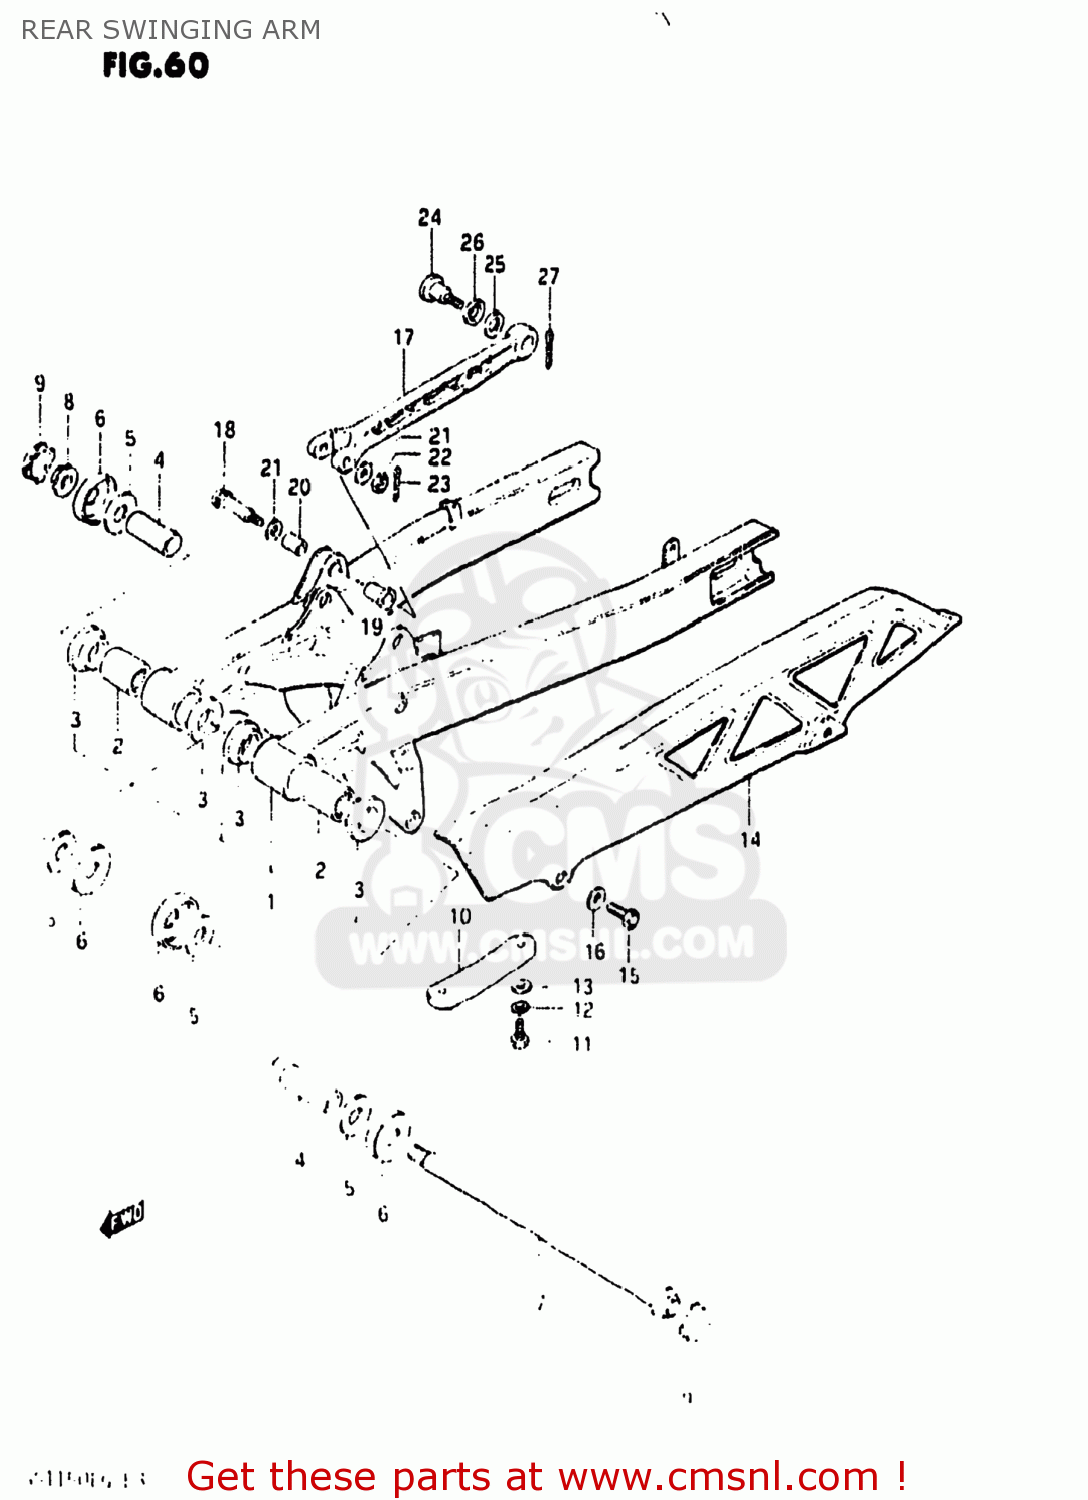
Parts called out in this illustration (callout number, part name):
1	ARM,REAR SWING
2	BEARING(25X33X30)
3	BUSHING
4	SPACER,RR SWINGING ARM PIVOT
5	WASHER
6	COVER,RR SWINGINGARM PIVOT
7	SHAFT,REAR SWING ARM
8	NUT
9	CAP,PIVOT
10	BUFFER,CHAIN TOUCH DEFENSE
11	BOLT
12	WASHER,LOCK
13	WASHER(6.5X18X1)
14	CASE,CHAIN
15	BOLT
16	WASHER
17	LINK,REAR TORQUE
18	BOLT 8X60
19	SPACER,REAR TORQUE LINK
20	SPACER,REAR TORQUE LINK
21	WASHER
22	NUT 8MM
23	PIN 20X20
24	BOLT,REAR TORGUE LINK,REAR
25	CUSHION
26	WASHER (18.5X28X2)
27	PIN 20X20
